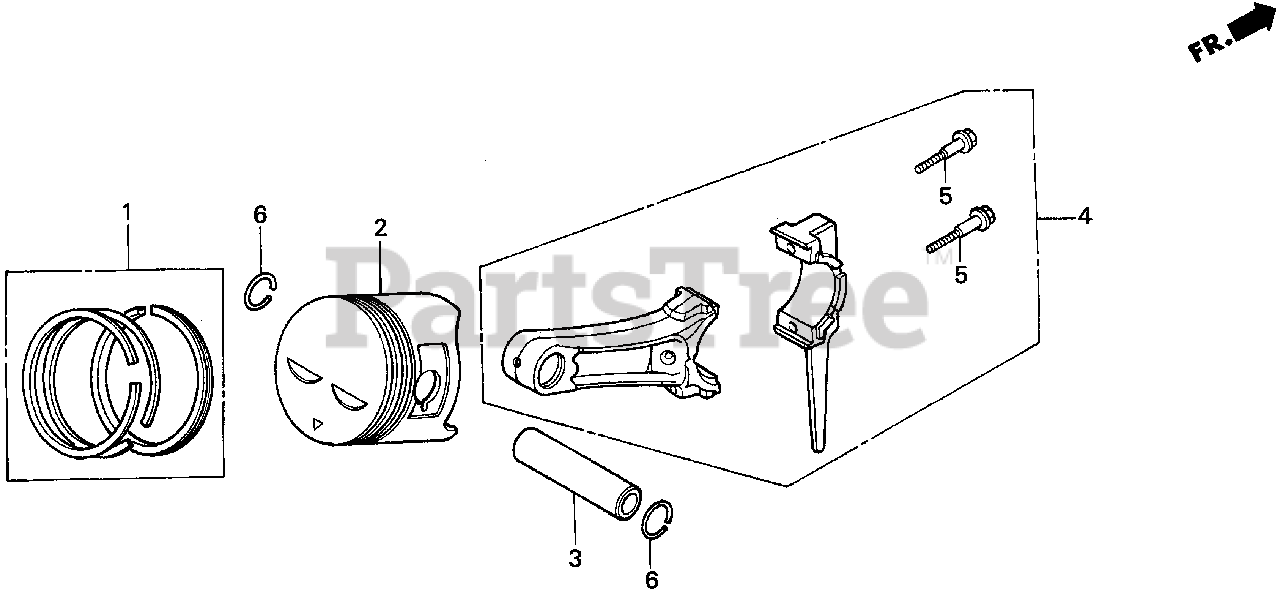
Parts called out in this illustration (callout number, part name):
1	RING SET, PISTON (STD)
1	RING SET, PISTON (STD) (NIPPON)
1	RING SET, PISTON (STD) (TEIKOKU)
1	RING SET, PISTON (OS 0.25) Use up to Engine SN 2623677.
1	RING SET, PISTON (OS 0.25) Use up to Engine SN 1281053.
1	RING SET, PISTON (0.25) (NIPPON) Use up to Engine SN 4081304.
1	RING SET, PISTON (OS 0.25) Use up to Engine SN 4081304.
1	RING SET, PISTON (OS 0.25) Use from Engine SN 4081305.
1	RING SET, PISTON (OS 0.50) Use up to Engine SN 2623677.
1	RING SET, PISTON (OS 0.50) Use up to Engine SN 1281053.
1	RING SET, PISTON (0.50) (NIPPON) Use up to Engine SN 4081304.
1	RING SET, PISTON (OS 0.50) Use from Engine SN 4081305.
1	RING SET, PISTON (OS 0.75) Use up to Engine SN 1242764.
1	RING SET, PISTON (OS 0.75) Use up to Engine SN 1281053.
1	RING SET, PISTON (0.75) (NIPPON) Use up to Engine SN 4081304.
1	RING SET, PISTON (0.75)
2	PISTON (STD)
2	PISTON (0.25)
2	PISTON (OS 0.25)
2	PISTON (OS 0.50)
2	PISTON (OS 0.75) Use up to Engine SN 1263002.
2	PISTON (OS 0.75)
3	PIN, PISTON
4	ROD ASSY., CONNECTING (STD)
4	ROD ASSY., CONNECTING (Honda Code 2110153). (US 0.25)
5	BOLT, CONNECTING ROD
6	CLIP, PISTON PIN (18MM)
